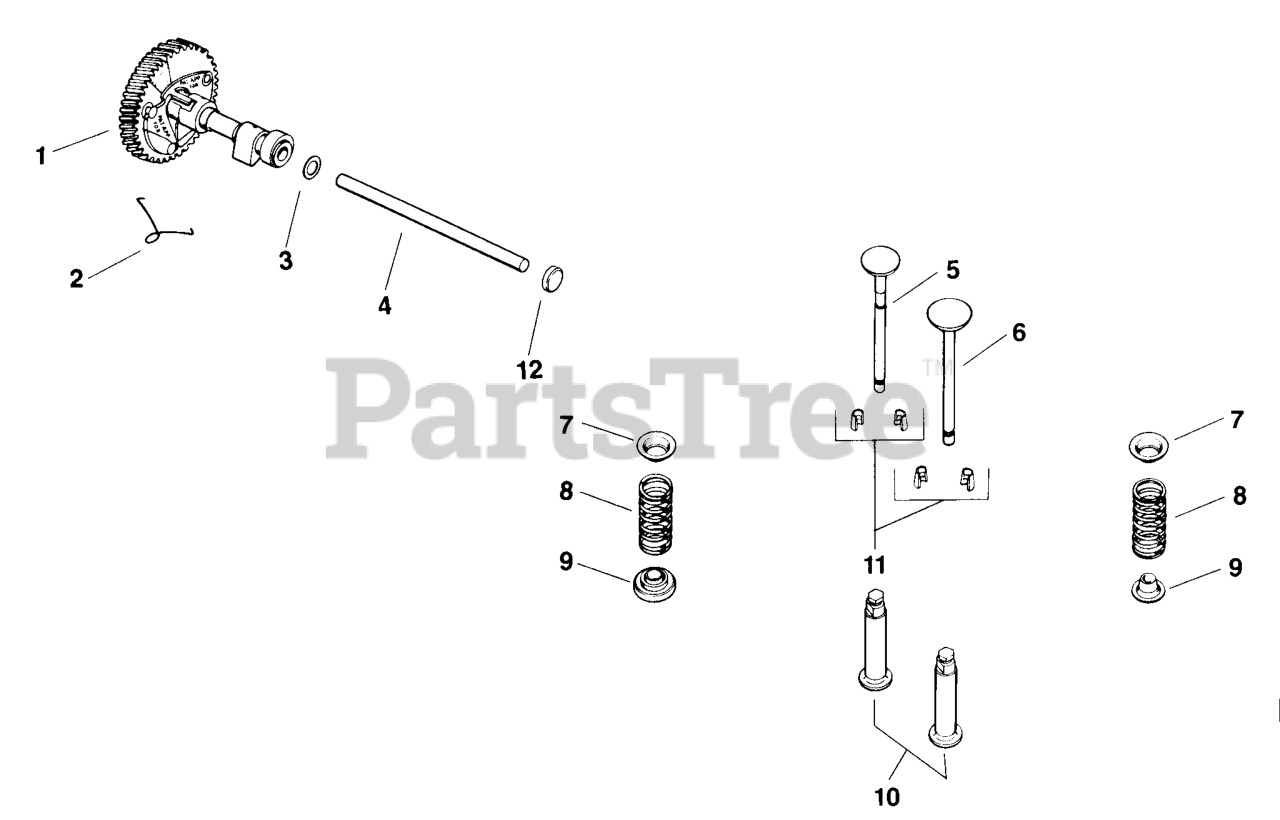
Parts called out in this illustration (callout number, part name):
1	CAMSHAFT ASSY - DISCONTINUED
2	SPRING, ACTUATING-DISCONTINUED
3	SPACER (.005")
3	SPACER (.010")
4	PIN, CAMSHAFT - DISCONTINUED
7	RETAINER, SPRING
8	SPRING, INTAKE VALVE - DISCONTINUED
9	ROTATOR - USE 52 413 01
11	KIT, RETAINER
12	PLUG, CUP 1/2" USE 25 139 50-S
